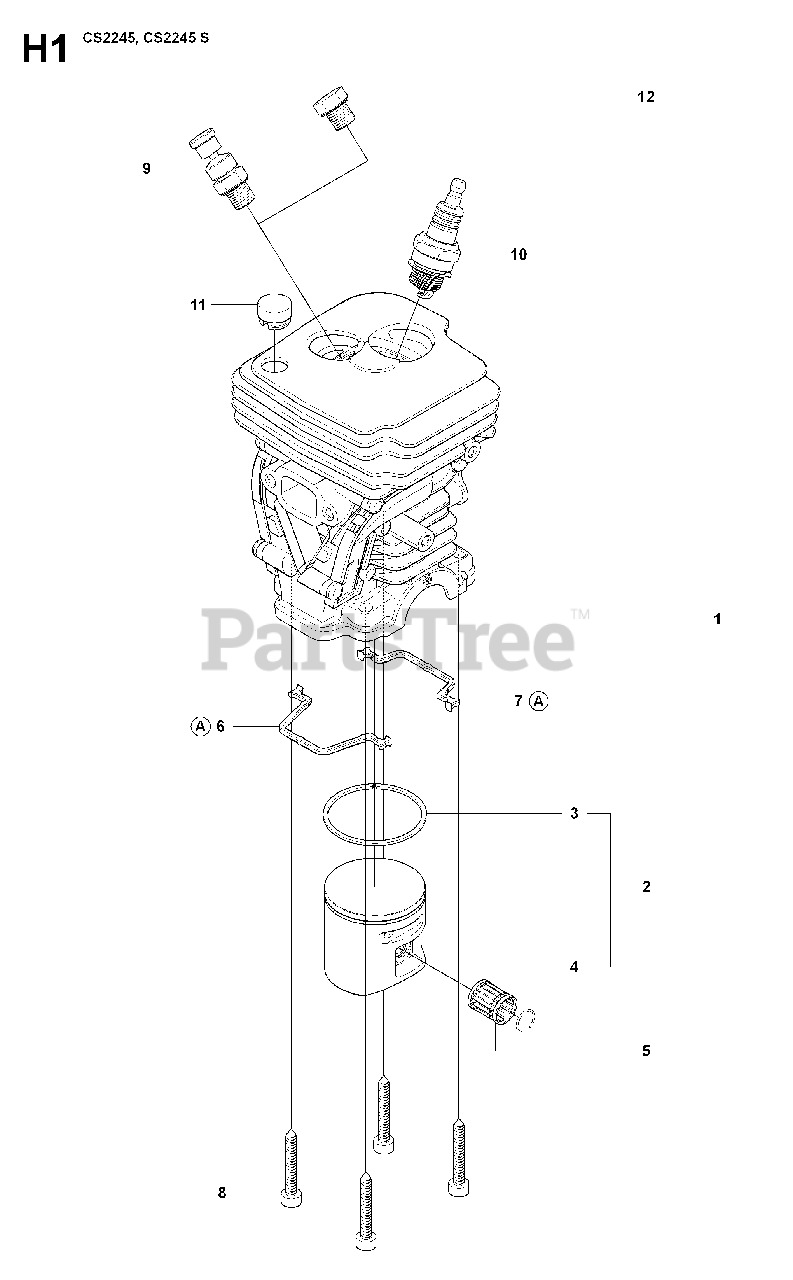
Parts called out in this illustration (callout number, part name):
2	PISTON ASSY
3	PISTON RING
5	RP SUPPORT BUSHING
9	DECOMPRESSION VALVE
10	BPMR7A NGK SPARK PLUG
12	CYLINDER PLUG
